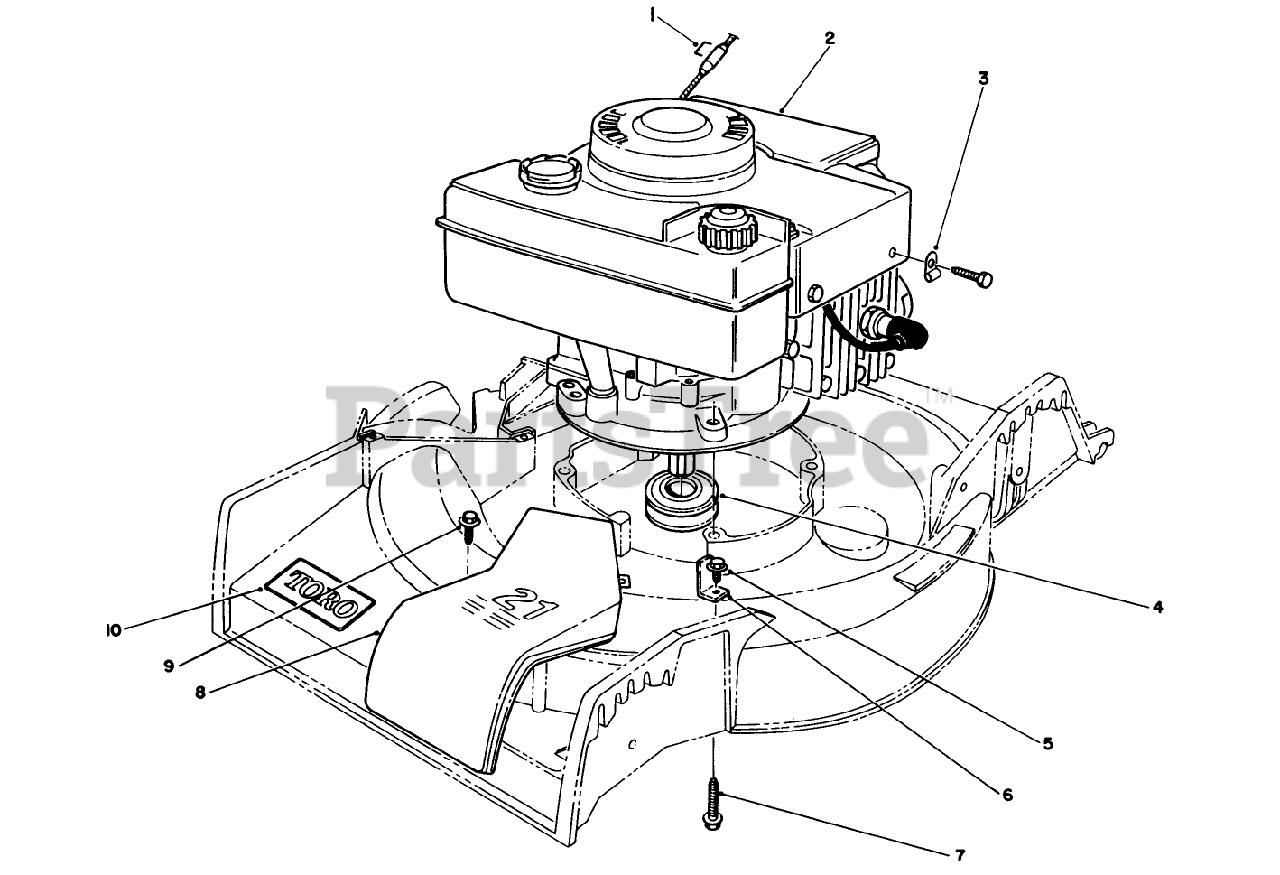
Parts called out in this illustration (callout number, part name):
1	Staple
2	Engine
4	PULLEY-DRIVER
5	SCREW-HWHTF
6	BELT GUIDE
7	3/8-16 X 2-3/4 CAPSCR
8	BELT COVER 21" S D
9	SCREW
10	DECAL
